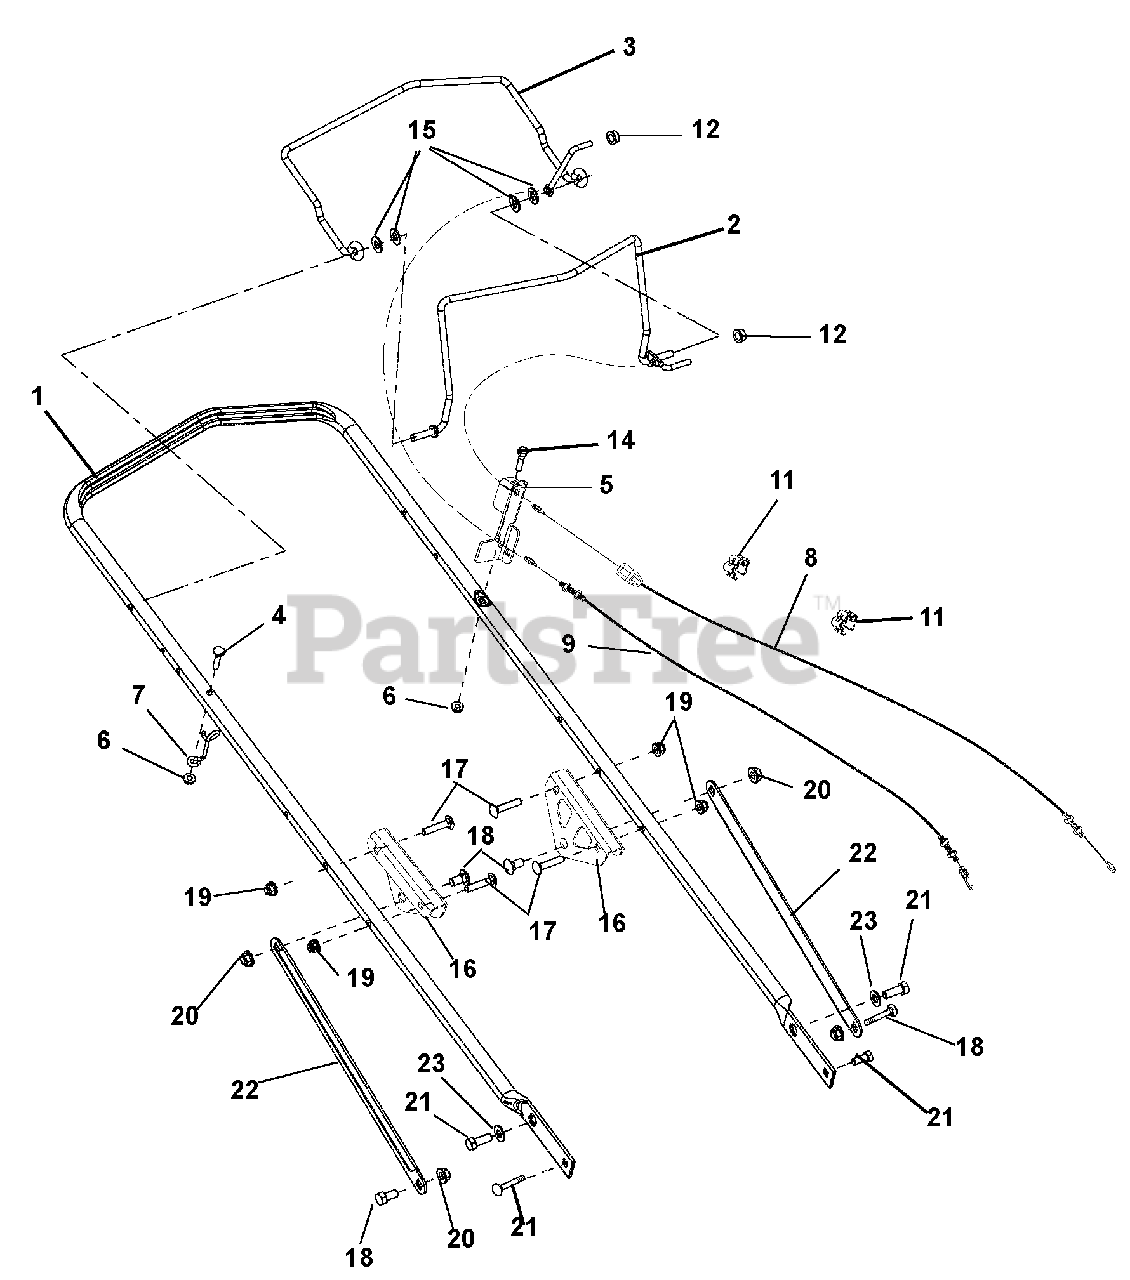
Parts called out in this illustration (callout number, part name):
1	Handlebar
2	Bail, Operator Presence
3	Bail, Clutch
4	Bolt, Round Head Square Neck .25-20 x 1.25
5	Anchor, Cable Thumb Adjustment
6	Nut-Locking-Top-Flange .25-20
7	Guide, Pullcord
8	Cable, Operator Presence Control
9	Cable, Commercial 21 Traction
10	Bolt, Hex .31-18 x .75 Grade 5
11	Clip, Conduit
12	Push Nut, .25
13	Plate, Hinge
14	Bolt, Hex .25-20 x 1.25 Grade 5
15	Washer, Flat-Steel .344 x .688 x .065
16	Bracket, Handlebar Reforcement
17	Bolt, Round Head Square Neck .31-18 x 1.50 Grade 5
18	Bolt, Round Head Square Neck .38-16X.75
19	Nut, .31-18 Nyloc Flange
20	Nut, .38-16 Nyloc Flange
21	Bolt, Hex .38-16 x .75 Grade 5
22	Strap, Handlebar
23	Washer, Flat-Steel .406 x .812 x .065
